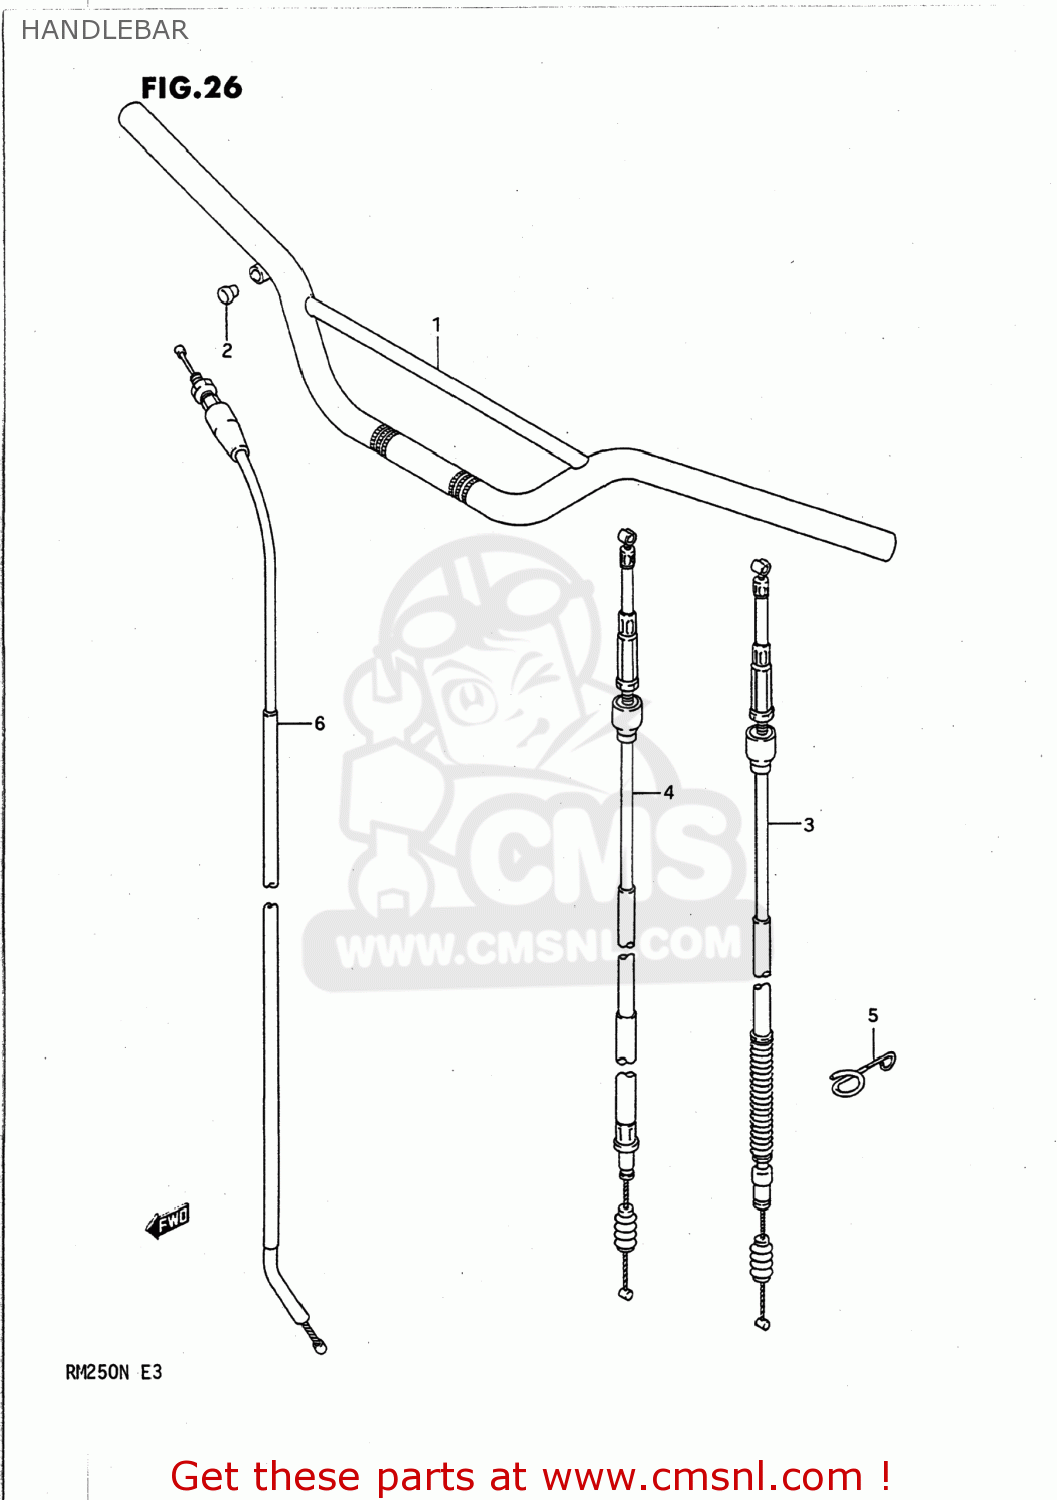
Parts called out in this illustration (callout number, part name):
1	HANDLEBAR
2	CAP(OD:14)
3	CABLE ASSY,CLUTCH
4	CABLE ASSEMBLY,CLUTCH
5	GUIDE,CLUTCH CABLE
6	CABLE ASSY,THROTTLE
